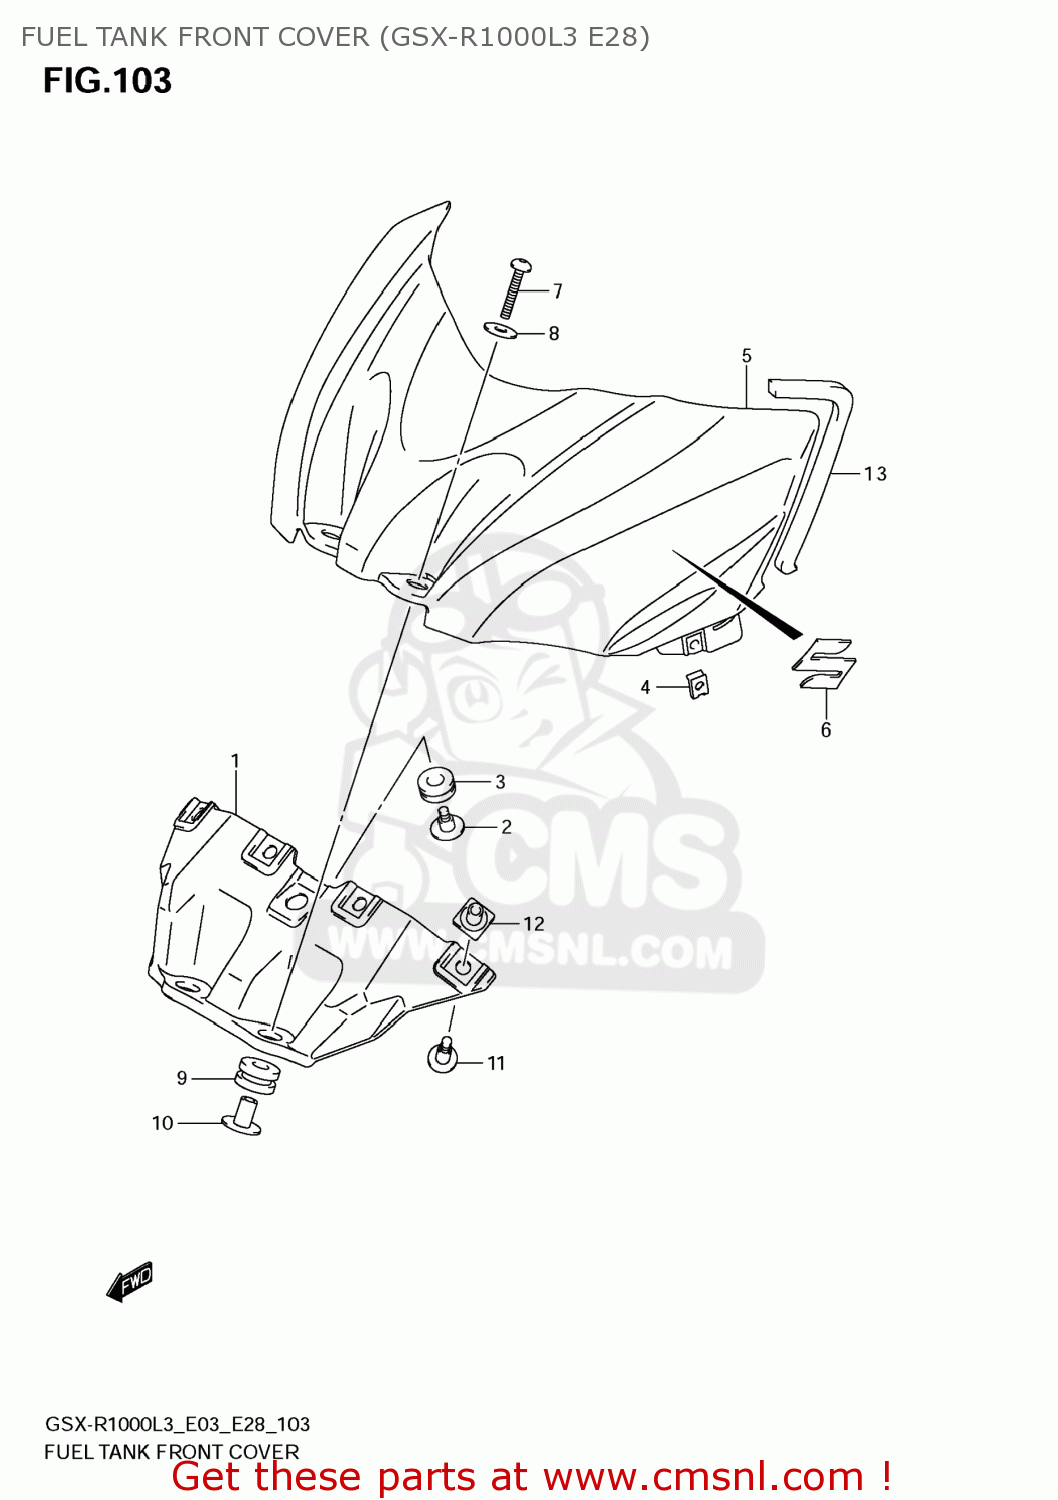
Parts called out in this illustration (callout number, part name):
1	BRACKET,FUEL TANK FR
2	SCREW(5X16.4)
3	CUSHION
4	NUT
5	COVER,FUEL TANK FR
6	EMBLEM,S
7	SCREW(6X40)
8	WASHER(6,5X22X1.6)
9	CUSHION
10	SPACER,FUEL TANK FR
11	SCREW(6X10)
12	NUT(M6)
13	CUSHION,FUEL TANK COVER
